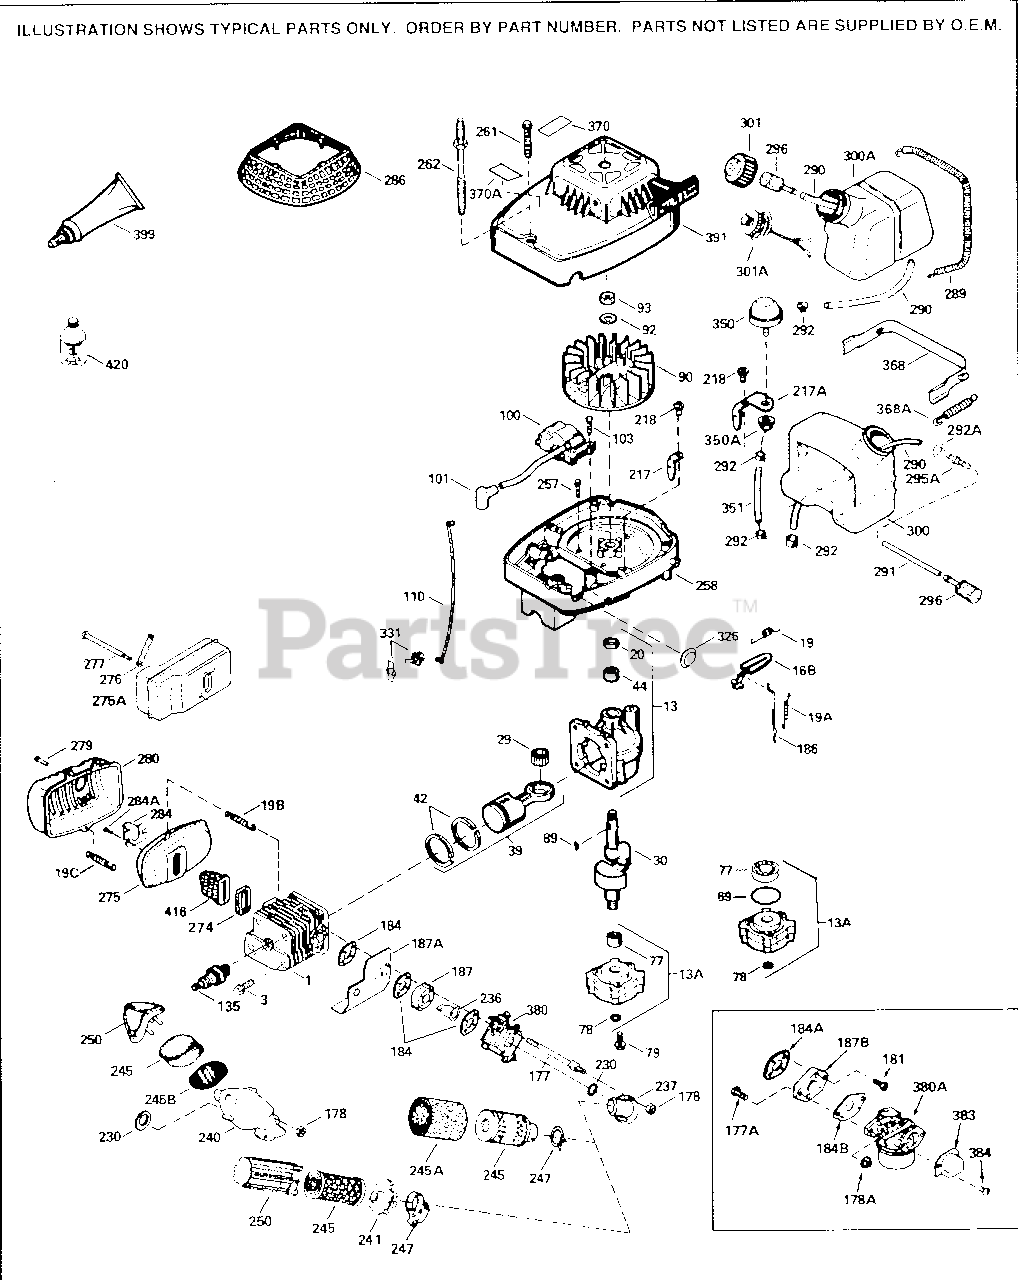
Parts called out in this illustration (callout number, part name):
1	"Cylinder (Incl. 119 & 187A)
3	Screw, Torx T-30, 1/4-20 x 43/64"
13	Crankcase Ass'y. (Incl. 20 & 44)
13A	Crankcase Cover Ass'y. (Incl.77 & 78)
16B	Air Vane
19	Governor Spring
19A	Backlash Spring
20	Oil Seal
30	Crankshaft
39	Piston & Rod Ass'y. (Incl. 42)
42	Ring Set
44	Cartridge Bearing
69	"O" Ring
77	Cartridge Bearing
78	Oil Seal
79	Screw, 1/4-20 x 3/4"
89	Flywheel Key
90	Flywheel
92	Belleville Washer
93	Flywheel Nut
100	Solid State Ignition (Incl. 101)
101	Spark Plug Cover
103	Screw, Torx T-15, 10-24 x 1"
110	Ground Wire
119	Cylinder Head Gasket
135	Resistor Spark Plug (RCJ6Y)
177	Carburetor Mounting Stud
178	Lock Nut, 10-24
184	Carburetor Gasket
186	Governor Link
187A	Air Baffle
217	Control Lever
218	Screw, 8-32 x 1/2"
230	"O" Ring
240	Air Cleaner Body
245	Air Filter
245B	Air Filter
250	Air Cleaner Cover
257	Screw, 10-24 x 1/2"
258	Blower Housing Base
261	Screw, 8-32 x 1-9/16"
274	Exhaust Gasket
275	Muffler (Incl. 274 & 277)
277	Screw, 1/4-20 x 2.409"
290	Fuel Line
292	Fuel Line Clamp
296	Fuel Filter
300	Fuel Tank (Incl. 290 & 296)
301	Fuel Cap
331	Toggle Switch
368	Fuel Tank Strap
368A	Fuel Tank Strap Spring
370	Instruction Decal
380	Carburetor (Incl. 184)
391	Rewind Starter & Housing Ass'y.
399	Gasket Eliminator (Loctite 515)
420	2-Cycle Oil with Fuel Stabilizer - 8 oz.
